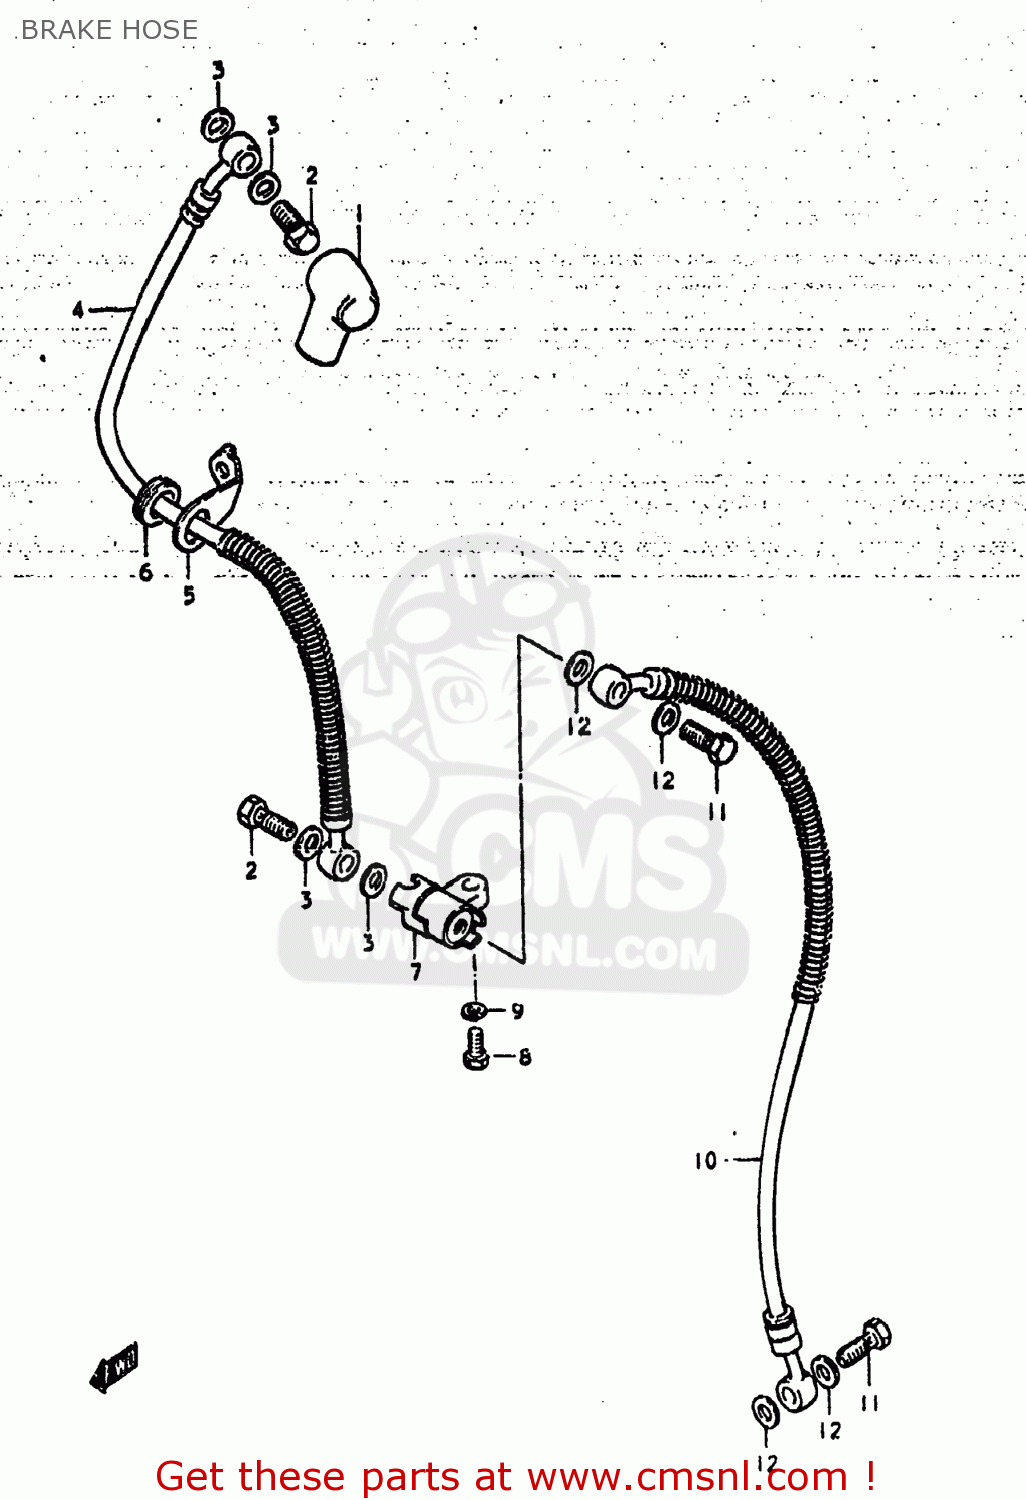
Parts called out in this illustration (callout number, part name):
1	BOOT,MASTER CYLINDER
2	BOLT UNION
3	WASHER
4	HOSE,FRONT BRAKE
5	GUIDE,BRAKE HOSE
6	GROMMET
7	JOINT,BRAKE HOSE
8	BOLT
9	LOCK WASHER
10	HOSE,BRAKE NO.2
11	BOLT UNION
12	WASHER
